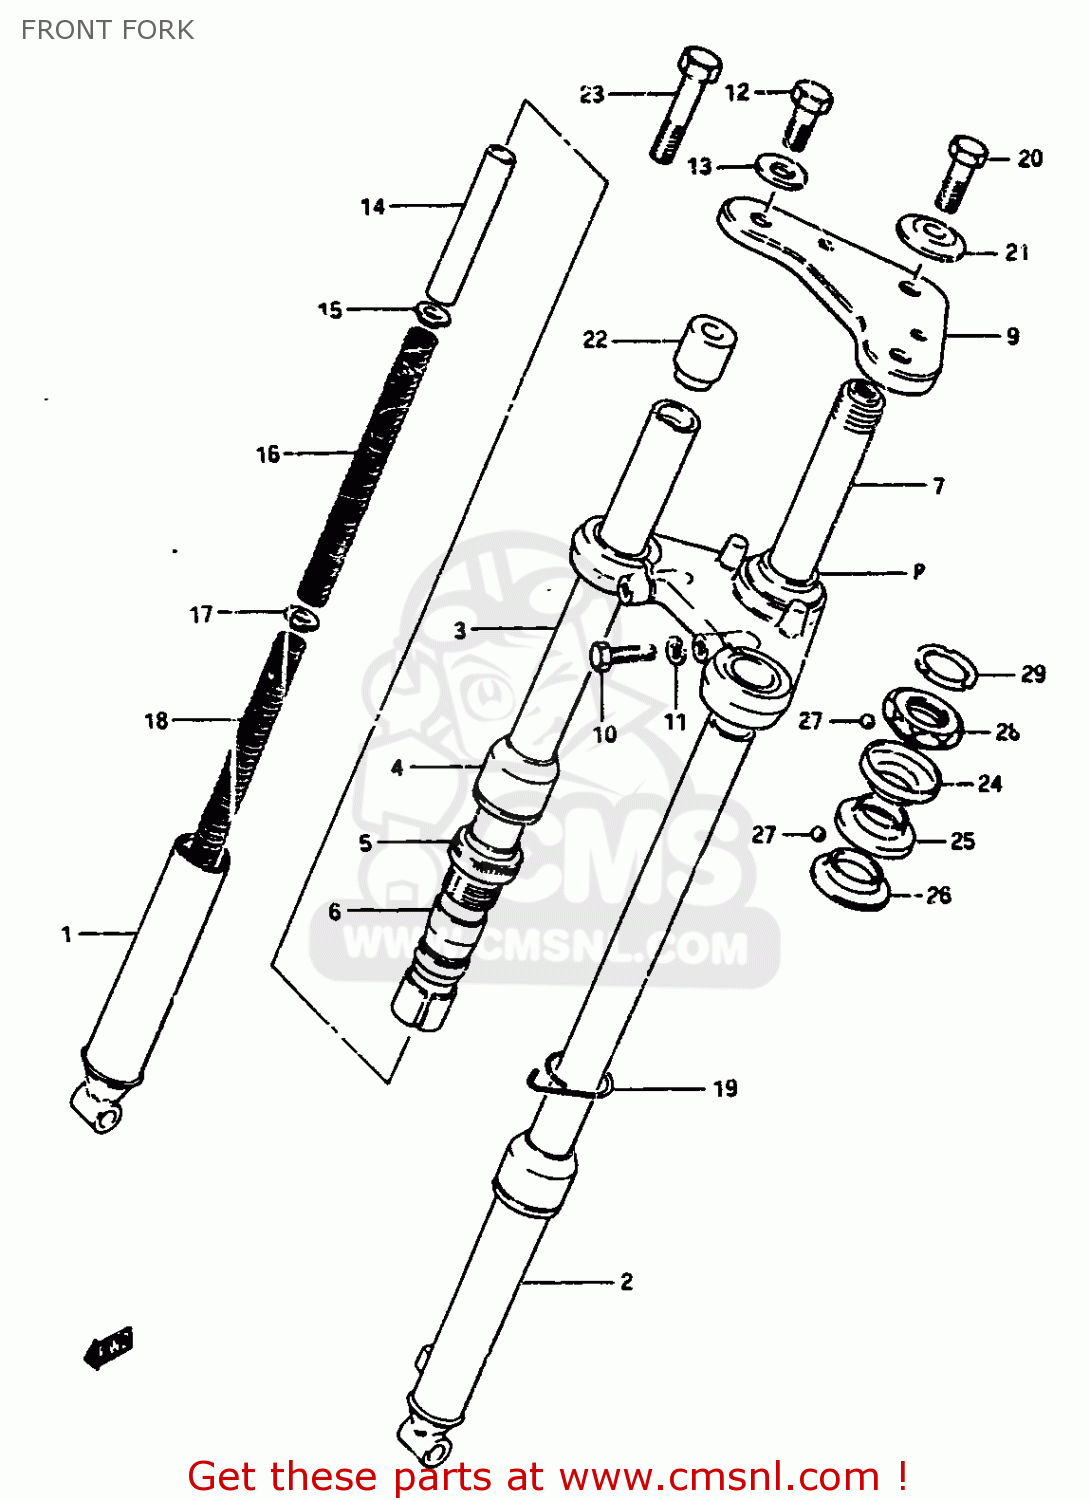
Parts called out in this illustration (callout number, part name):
1	TUBE,OUTER,RIGHT
2	TUBE,OUTER,LEFT
3	TUBE,INNER
4	SEAL,DUST
5	NUT,OUTER
6	STOPPER
7	STEM,STEERING
8	HEAD,STEERING STEM
9	BOLT
10	LOCK WASHER
11	BOLT
12	WASHER,STEERING STEM HEAD
13	SPACER
14	GUIDE,SPRING
15	SPRING,NO.1
16	GUIDE,SPRING NO.2
17	SPRING,NO.2
18	CLIP
19	BOLT
20	WASHER(33.5X10.5X4.2)
21	SPACER,FR FORK INNER TUBE
22	BOLT,FRONT FORK INNER TUBE
23	RACE,STEERING,INNER,UPPER
24	RACE,STEERING,INNER,LOWER
25	RACE,STEERING,OUTER,LOWER
26	BALL
27	RACE,STEERING,OUTER,UPPER
28	NUT,STEERING STEM
